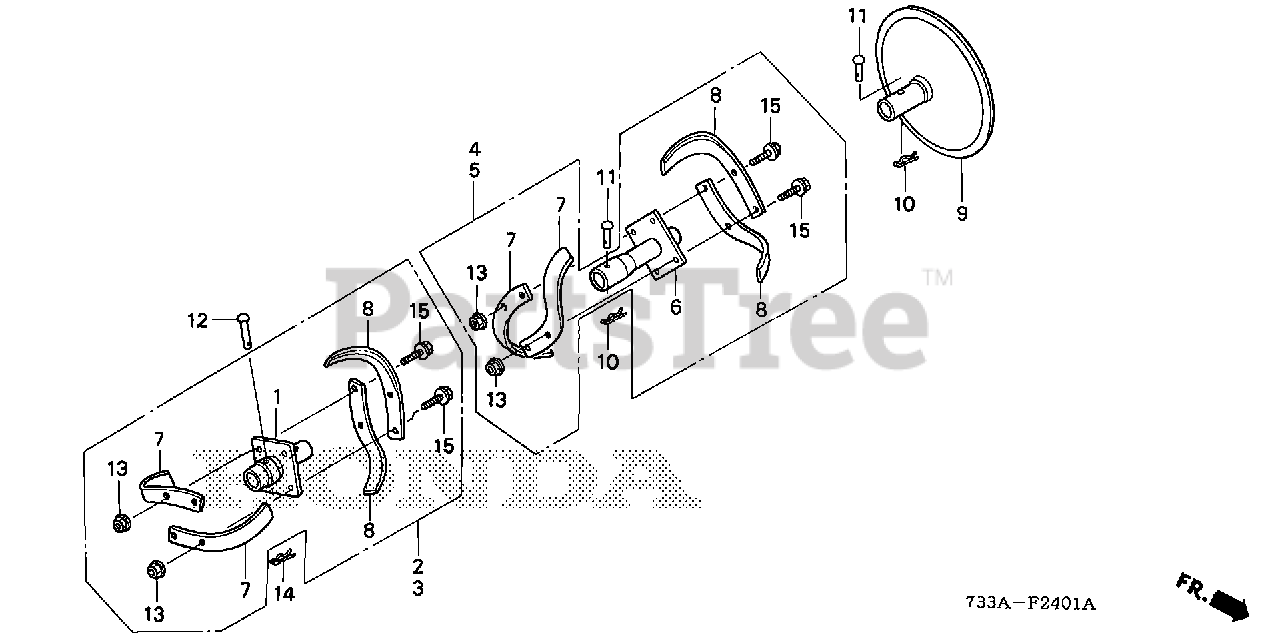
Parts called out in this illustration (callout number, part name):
1	PIPE, MAIN ROTOR
1	PIPE, MAIN ROTOR (NOT AVAILABLE)
2	ROTOR ASSY., R. MAIN (NOT AVAILABLE)
3	ROTOR ASSY., L. MAIN
3	ROTOR ASSY., L. MAIN (NOT AVAILABLE)
4	ROTOR ASSY., R. (OUTER) (NOT AVAILABLE)
5	ROTOR ASSY., L. (OUTER) (NOT AVAILABLE)
6	PIPE, ROTOR (OUTER)
7	TINE A, ROTOR
8	TINE B, ROTOR
9	DISK, SIDE
10	PIN, LOCK (10MM)
11	PIN, WHEEL (8X43)
12	PIN (10X53.5)
13	NUT, FLANGE (8MM)
14	PIN, LOCK (10MM)
15	BOLT, FLANGE (8X20)
